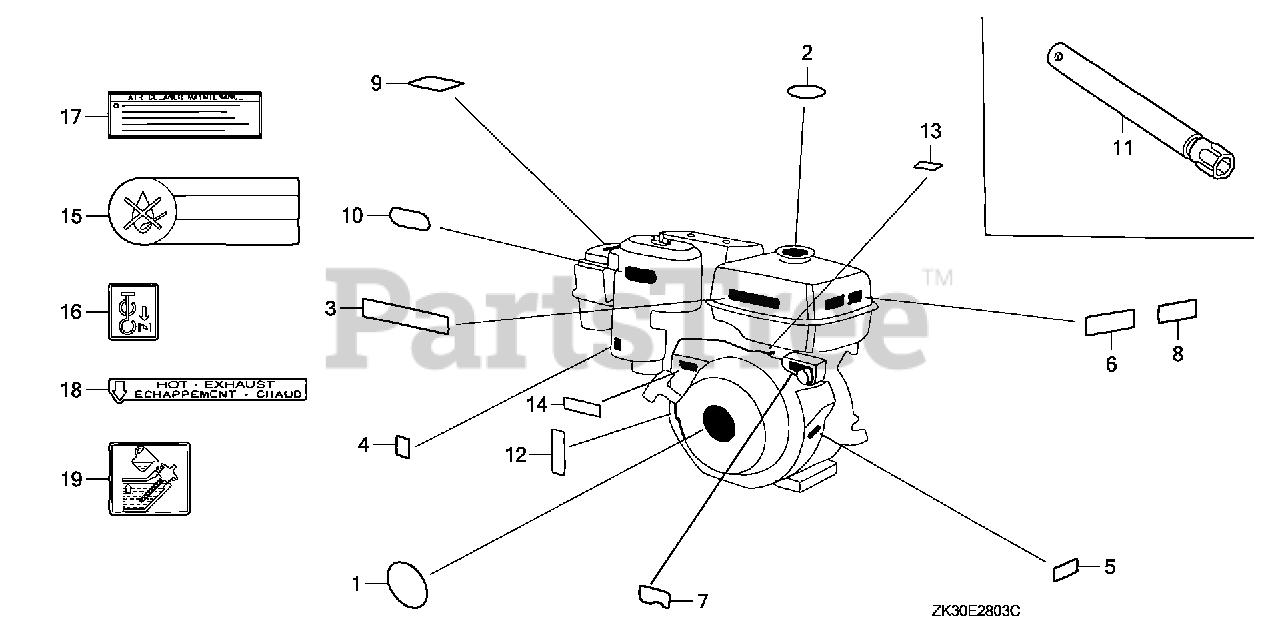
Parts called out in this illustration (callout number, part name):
1	EMBLEM (11. (HONDA)
3	LABEL, CAUTION (ENGLISH, ETC.)
4	MARK, CHOKE (ORANGE)
6	MARK, OIL ALERT (GERMAN)
6	MARK, OIL ALERT (FRENCH)
8	MARK, OIL ALERT (ENGLISH)
9	LABEL, AIR CLEANER CAUTION
10	MARK, AIR CLEANER SALES POINT
